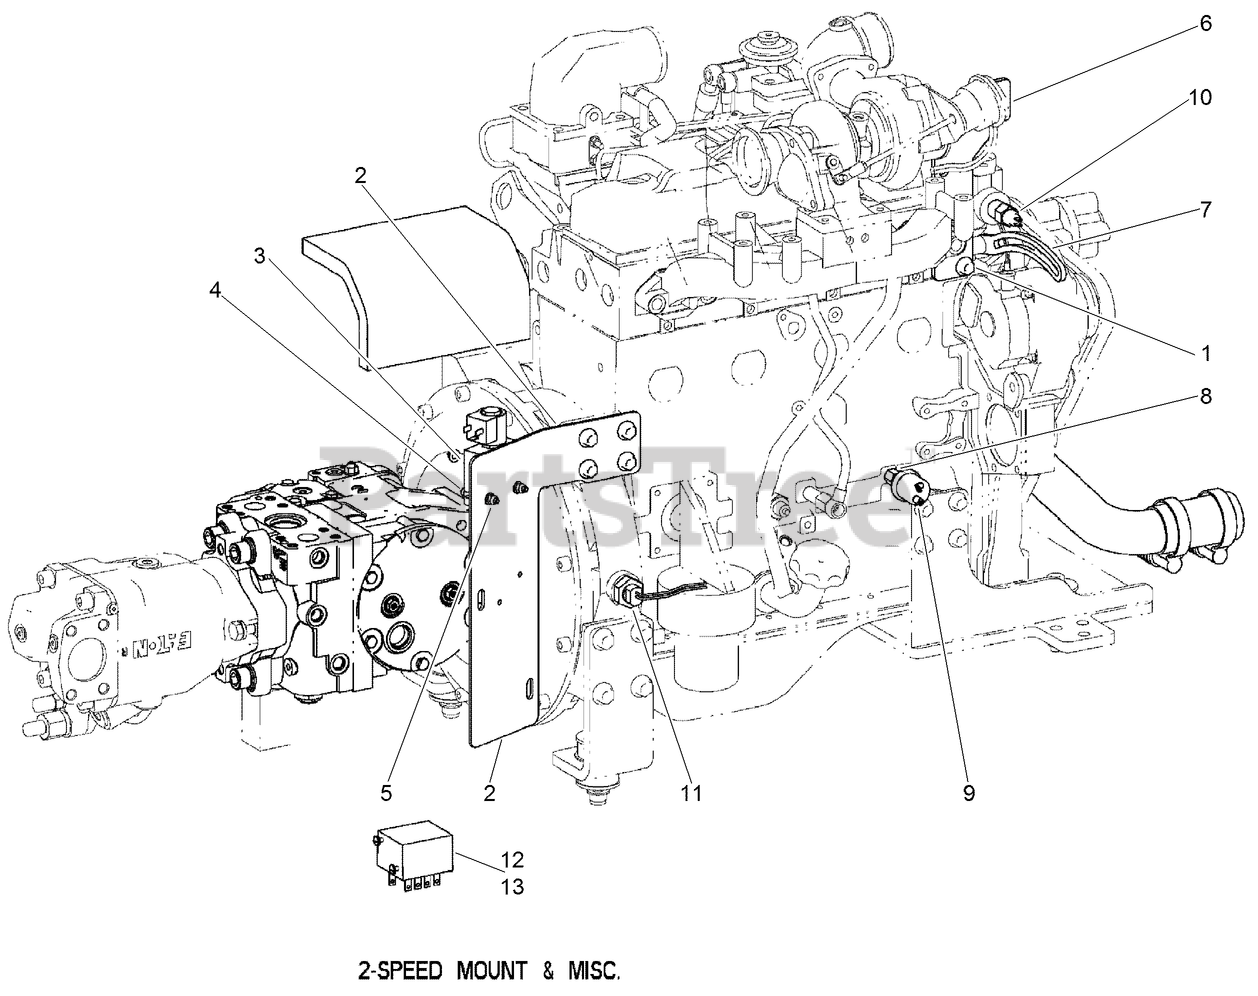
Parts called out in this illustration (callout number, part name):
1	SCREW-FLANGE
2	MOUNT - Cold Start
3	VALVE - Dir, Cart, 3W2P, SOL, 12VDC
4	SCREW, METRIC FLANGE w/BODY - M6 x 45
5	NUT, METRIC FLANGE PREVAILING - M6 Zinc
6	PLATE-HOIST POINT
7	BRACKET-Alternator
8	ADAPTER - Pipe
9	SENSOR-PRESSURE, OIL
10	SENSOR-COOLANT
11	SENSOR-RPM, MAG PICKUP
12	RELAY-CONTROL, ENGINE
13	SCREW - PHd Sltd # 10-24 x 0.75 CST ZND
